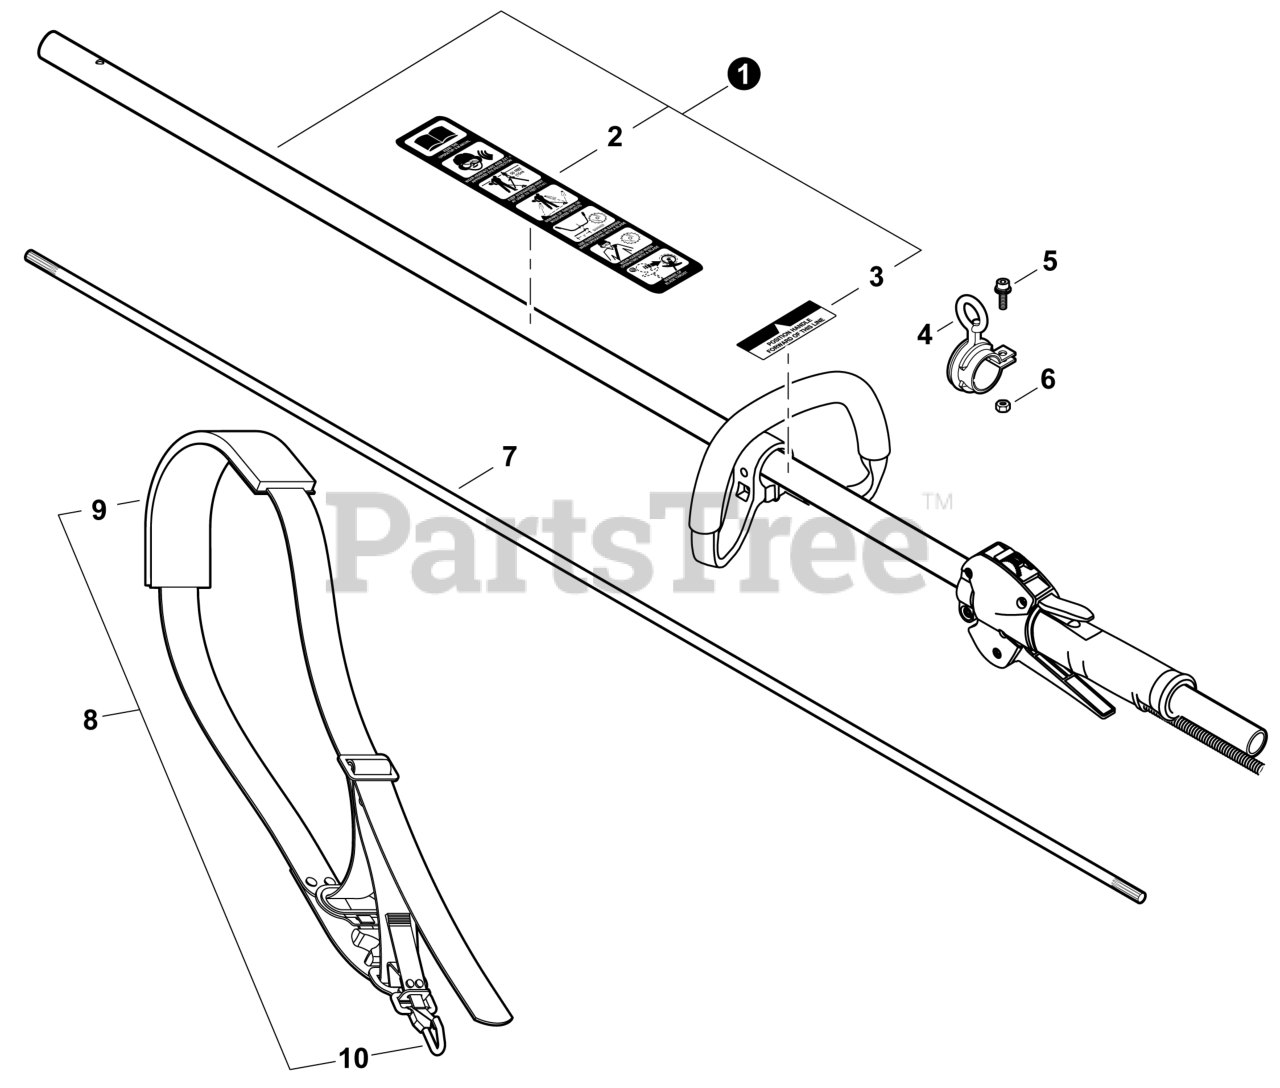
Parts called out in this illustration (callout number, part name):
1	MAIN PIPE ASSY
2	LABEL - CAUTION (BLADE CAPABLE)
3	LABEL - HANDLE
4	HANGER, SWIVEL
5	BOLT 5
7	MAINSHAFT
8	HARNESS ASSY, SHOULDER
9	PAD, SHOULDER
10	HOOK, SNAP
